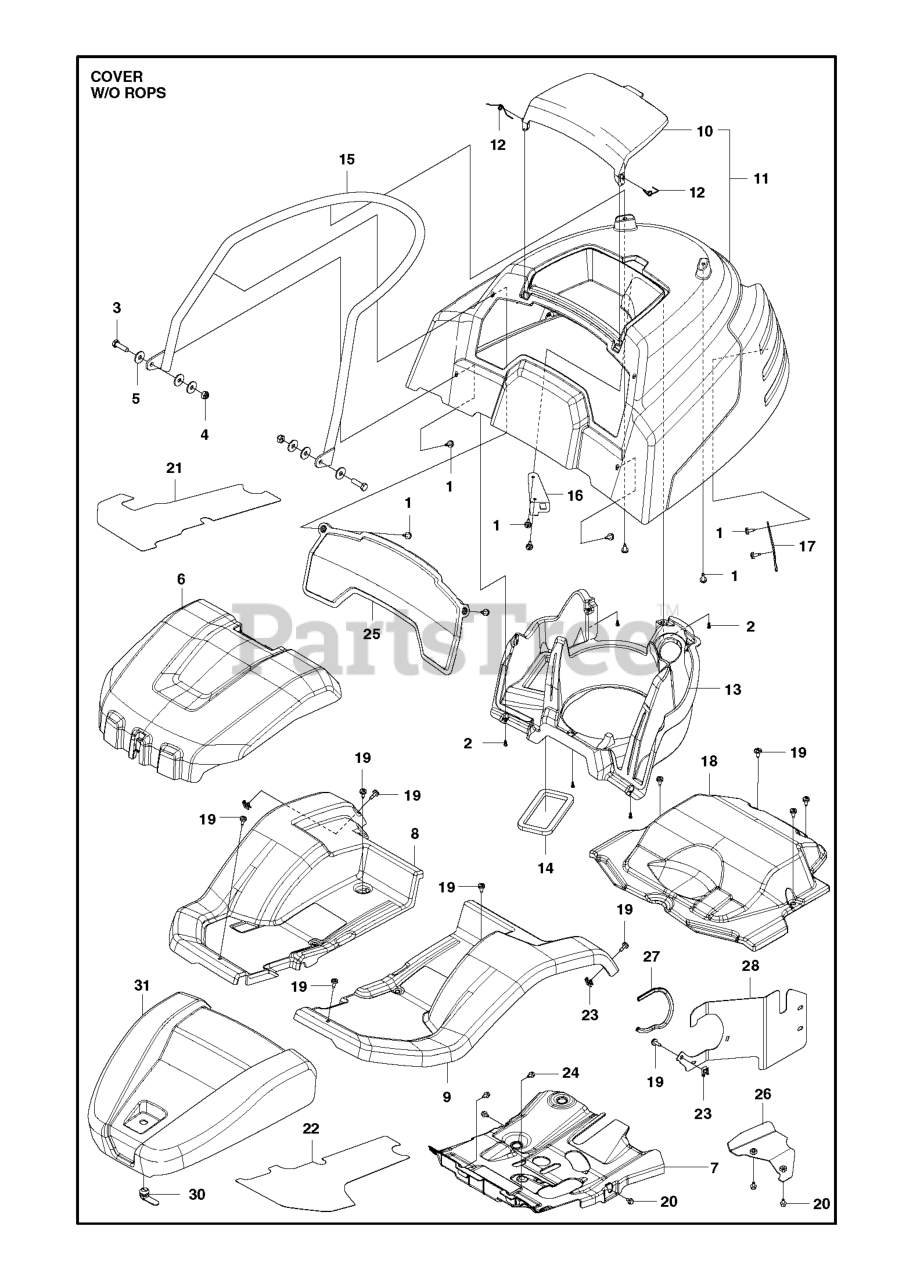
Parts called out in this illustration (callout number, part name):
1	SCREW
4	NUT
7	COVER FRONT BELT COVER P524
